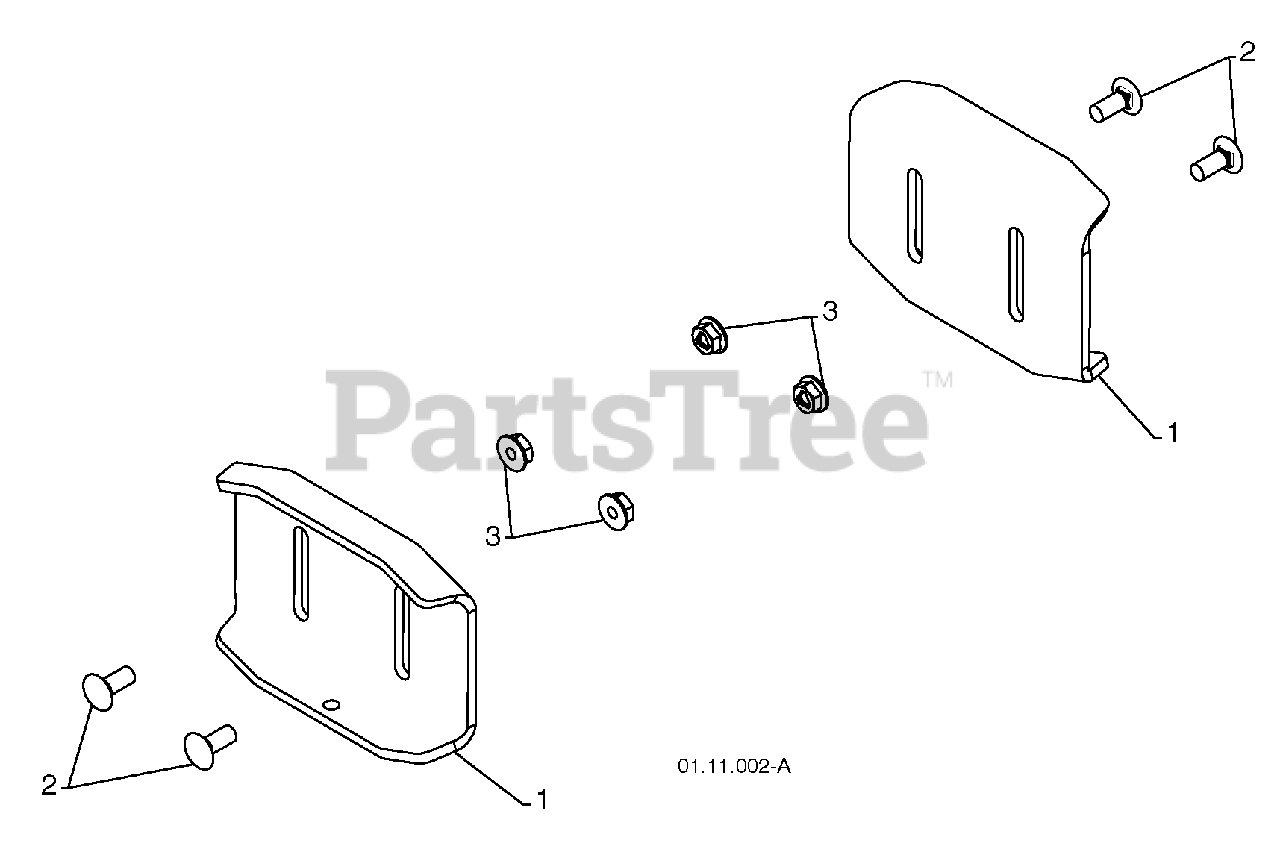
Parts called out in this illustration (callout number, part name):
1	SKID PLATE
2	CARRIAGE BOLT 5/18-18 X .750
3	NUT 5/16-18
